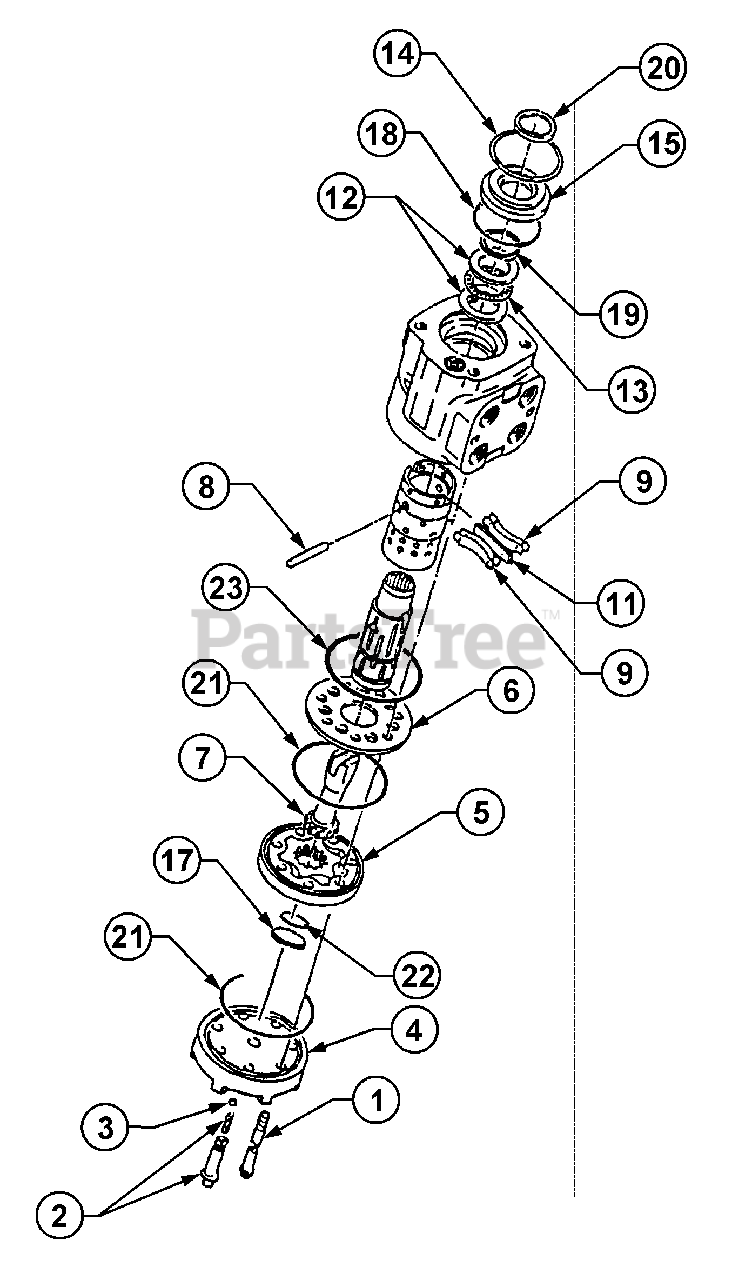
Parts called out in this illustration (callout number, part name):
2	Retainer Screw
6	Plate, Spacer
9	Spring, Centering
13	Bearing, Needle
18	O-Ring
19	Oil Seal
20	Seal, Dust
23	O-Ring
